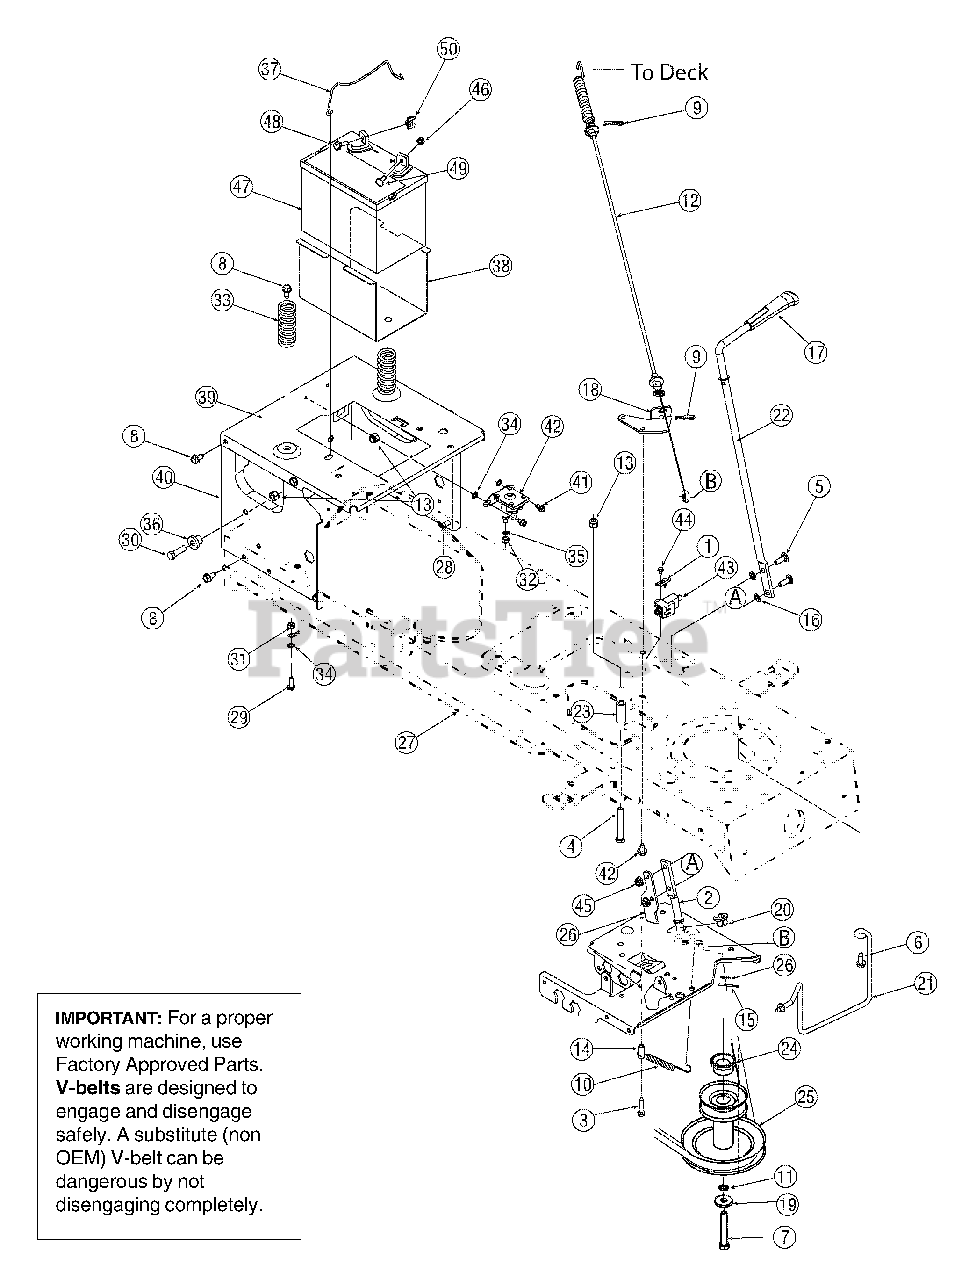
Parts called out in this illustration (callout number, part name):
1	Plate, Switch
2	Lever Assembly, Engagement
3	Screw, 1/4-20 x 1.250
4	Screw, 3/8-16, 2.50
5	Screw, Carriage, 5/16-18, 1.00
6	Screw, 5/16-18 x.750
7	Screw, 7/16-20, 3.25, Gr5
8	Screw, 5/16-12, 0.750
9	Click Pin
10	Extension Spring,.38OD x 3.9LG
11	Lock Washer, 7/16
12	Deck Engagement Cable
13	Nut, Flange Lock, 3/8-16, Gr F, Nylon
14	Spacer,.260 x.372 x 1.030LG
15	Pin, Cotter, 1/8 x 1.25
16	Nut, Speed,.3125 ID
17	Knob, PTO
20	Bearing, Flange, Hex Split.500 ID
21	Keeper Rod, Belt
23	Spacer,.385 ID x.635 OD x 1.54
24	Spacer, 1.010 x 1.400 x.825
25	Pulley, Engine, 3.39 x 6.12 Diameter
29	Screw, 1/4-20, 0.750
30	Screw, 3/8-16, 1.25, Gr5
31	Nut, Flange Lock, 1/4-20, Gr F, Nylon
32	Nut, Hex, 1/4-20, Gr5
33	Spring, Compression, 1.28 OD x 3.125
34	Washer, Lock, 1/4, External
35	Washer, Lock, 1/4
36	Spacer, Shoulder,.38 x 1.0 x.70
37	Hold Rod, Battery
41	Screw, 1/4-20, 0.50
42	Solenoid, 12V, 100 Amp
43	Switch, Interlock
44	Screw, #10-16,.50
45	Nut, Flange, Lock Nut, 5/16-18
46	Nut, Sems, 1/4-20
47	Battery, 190 CCA
48	Screw, Shoulder,.250 x.15, 1/4-20
49	Screw, Carriage, 1/4-20,.75
50	Nut, Wing, 1/4-20
